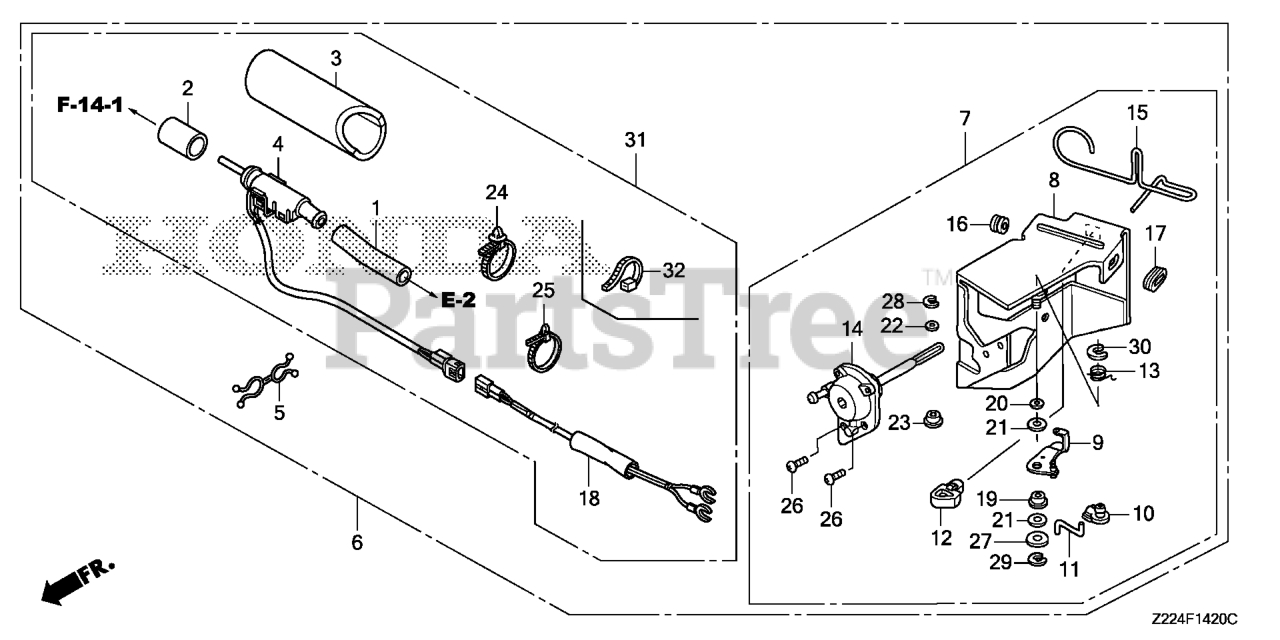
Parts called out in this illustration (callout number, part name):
1	TUBE, BREATHER (NOT AVAILABLE)
2	TUBE B, BREATHER
3	INSULATOR, BREATHER TUBE (NOT AVAILABLE)
4	HEATER ASSY., BREATHER (S) (NOT AVAILABLE)
18	SUB-WIRE ASSY.
24	CLIP, HARNESS BAND (145MM) (BLACK)
31	HEATER KIT, BREATHER
32	TIE, CABLE (C)
